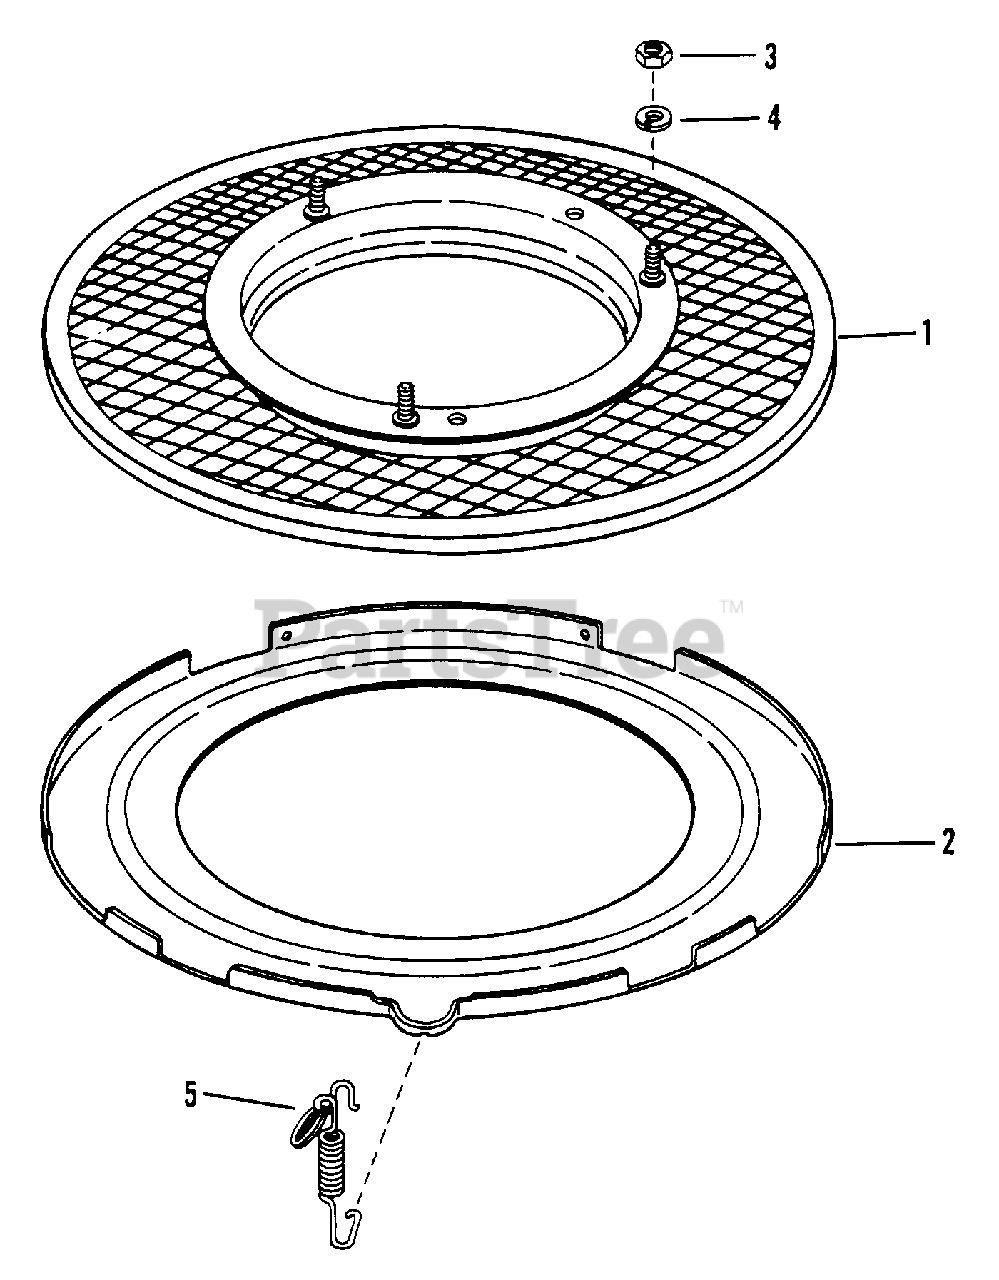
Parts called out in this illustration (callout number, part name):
1	ASSEMBLY, Screen Fastener
2	RING, Bottom
3	NUT, 5/16-24 Hex
4	WASHER, 5/16 Split Lock
5	SPRING
